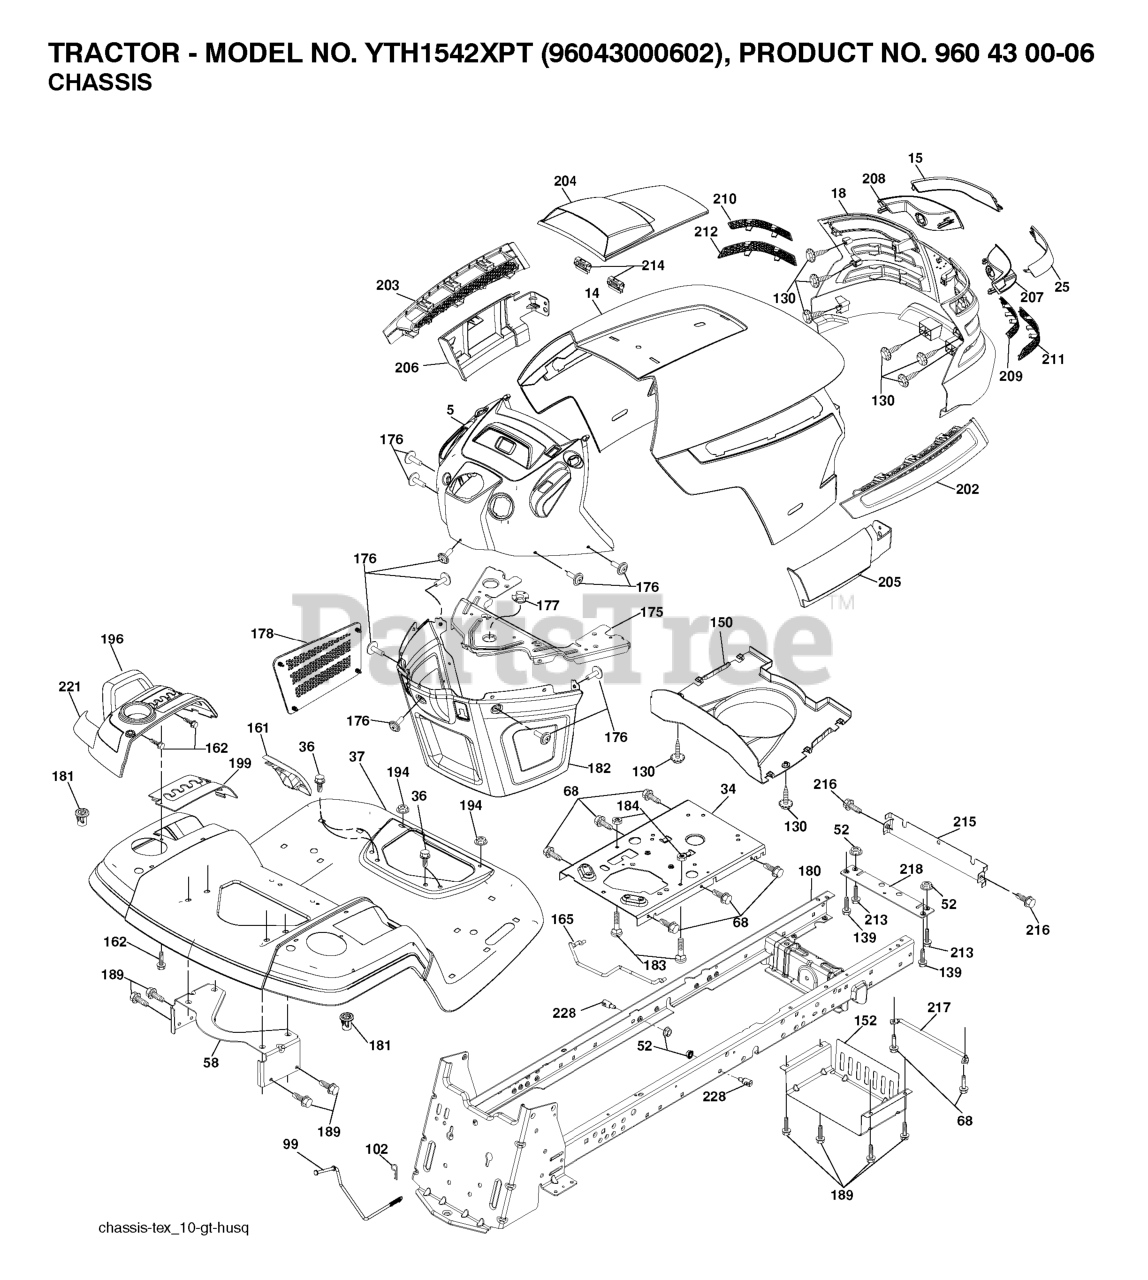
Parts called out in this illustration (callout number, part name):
5	DASH.HUSQ.UPR.ELE.SVMD
14	HOOD.PNT.HUSQVARNA.GT.
15	LENS.LH.TEX.GT.HUSQ.CL
18	GRILLE.ASM.TX.GT.HUSQ
25	LENS.RH.TEX.GT.HUSQ.CL
34	PLATE.ENGINE.WELDED.CHASSIS
36	SCREW 5/16"
37	FENDER.PNT.TX.GT.CH/FW.ORANGE
52	LOCKNUT
58	BRKT.SUPPORT.FNDR/TANK
68	Screw 5/16-18 x 1/2 Hex, Self Tapping 5/16-18 x 1/2
99	ROD.BYPASS.K46.TG
102	RETAINER M
130	SCREW
139	BOLT, SHOULDER 5/16-18
150	AIR.DUCT.TEXGT.HUSQ.31
152	SHIELD.BROWNING.WTEXLT
161	CONSOLE.FUEL.WINDOW.HU
162	SCREW.HI-LO.CONSOLE
165	SUPPORT.TANK.REAR.W/TEX
175	PLATE.CROSSMEMBER.HUSQ
176	SCREW.#10-24X5/8.RN.QU
177	BUSHING, STEERING
178	CARGO.ASM.NET.TXGT.W/C
180	CHASSIS.WLDMT.TX.GT.05
181	BUSHING.MNT.FEND.CRGO.
182	DASH.LOWER.COMMON.12V.
184	SPACER.FENDER
189	SCREW
194	NUT LOCK HEX FLANGE 5/16-18
196	RP CONSOLE.ASM.DECKLFT.W/
199	PLATE.DECK.LIFT.HUSQVARNA.GT
202	VENT.SIDE.HOOD.HUSQ.RH.GREY
203	VENT.SIDE.HOOD.HUSQ.LH.GRAY
204	VENT.TOP.HOOD.HUSQVARN
205	SKIRT.HOOD.SIDE.HUSQ.RH.GREY
206	SKIRT.HOOD.SIDE.HUSQ.LH.GREY
207	BEZEL.RH.TEX.GT.HUSQ
208	BEZEL.LH.TEX.GT.HUSQ
209	INSERT.HEX.GRILL.HUSQ.GREY
210	INSERT.HEX.GRILL.HUSQ.
211	INSERT.HEX.GRILL.HUSQ.
212	INSERT.HEX.GRILL.HUSQ.
213	BOLT
214	CLIP.RETAINER.TINNER.
215	COVER.CHASSIS.FRONT.WE
216	SCREW, 5/16-18 X 1/2
217	ROD PIVOT CHASSIS/HOOD
218	X-PIECE.HOOD.STOP.NON/
221	REFLECTOR.LH.TEX GT HU
228	STUD.FASTNER.W/ANTI-ROTATE
